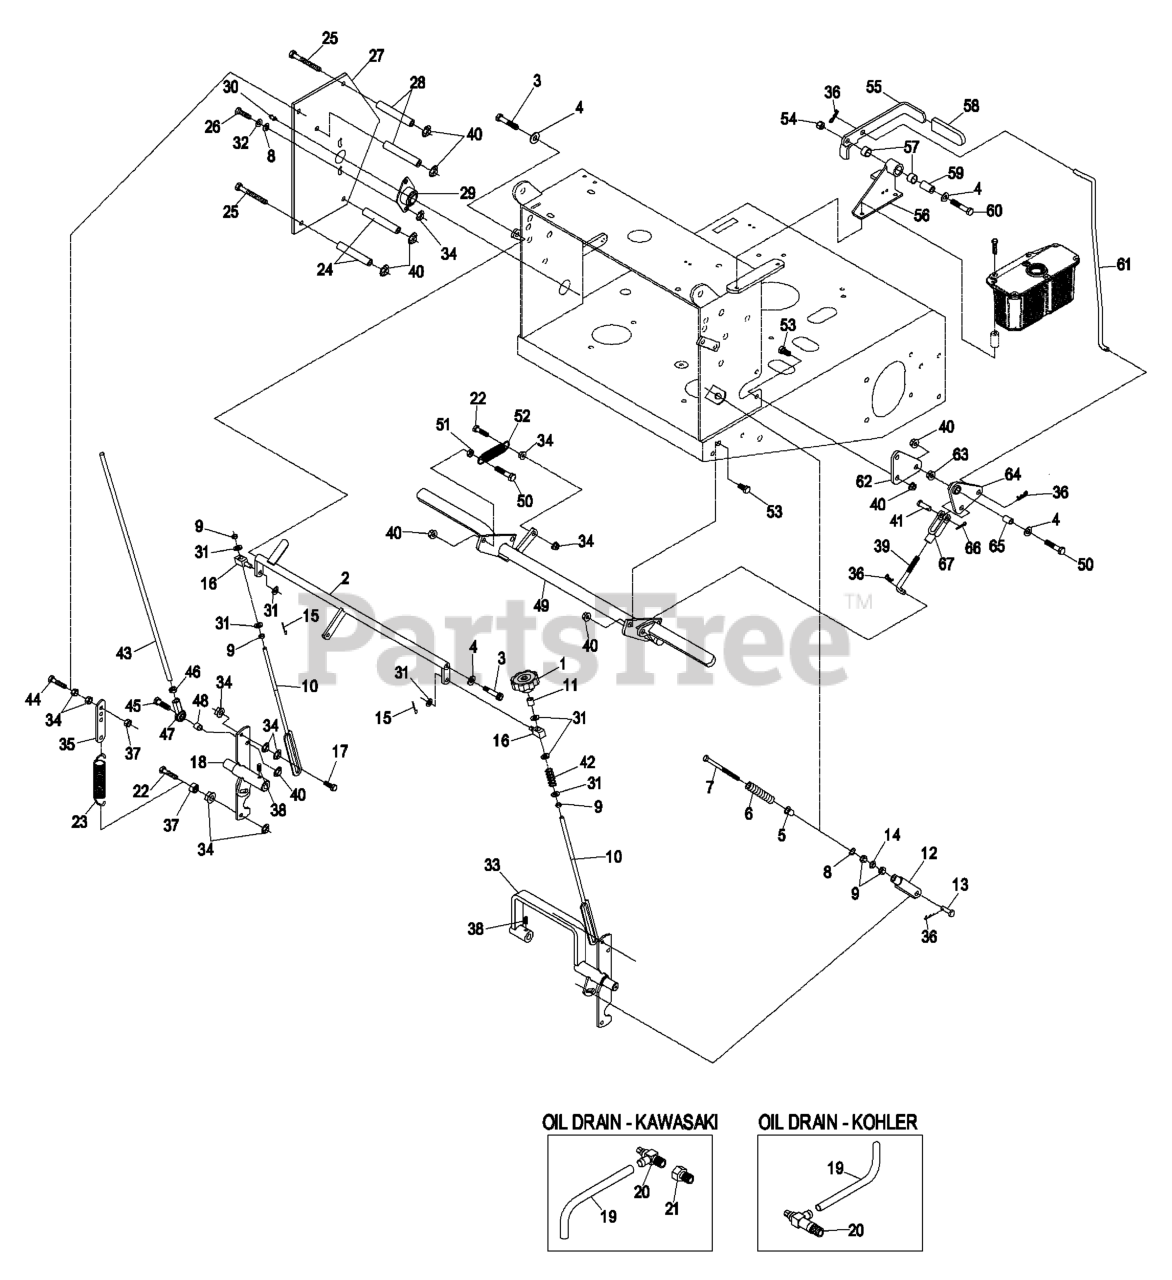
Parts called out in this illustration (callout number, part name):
1	KNOB-TRACKING
2	CRANK-CONTROL, SPEED
3	SCREW-HSH
4	WASHER-FLAT
5	BUSHING-FLANGED
6	SPRING,COMPRESSION (NEUT)
7	BOLT-RETURN, NEUTRAL
8	WASHER-FLAT
9	NUT-HEX
10	LINK-CONTROL, SPEED
12	YOKE-ADJUSTABLE
13	PIN-CLEVIS
14	NUT-JAM
15	PIN-COTTER
17	SCREW-HH
18	SHAFT-CONTROL, LH
19	HOSE-DRAIN, OIL
20	VALVE-DRAIN, OIL
21	ADAPTER
22	SCREW-HH
23	SPRING-EXTENSION
24	SPACER-SHIELD
25	SCREW-HH
26	SCREW-HH
28	SPACER-SHIELD
29	BEARING-FLANGE, SIDE
30	FITTING-GREASE
31	WASHER-PLAIN
32	WASHER-LOCK
35	TAB-SPRING, EXTENSION
36	PIN-COTTER
37	NUT-LOCK, NI
38	SCREW-SET
39	LINKAGE-LOWER
40	NUT-HHF, WHIZ
41	PIN-CLEVIS
42	SPRING-COMPRESSION
43	LINKAGE,DRIVE (PLT)
44	BOLT-TAP, HH
45	SCREW-HH
46	NUT-HEX JAM, LH
47	JOINT-BALL END, LH
48	SPACER-TUBE, PUMP LINK
49	WLD,PARK BRAKE 32
50	SCREW-HH
51	NUT-JAM
52	SPRING-IDLER
53	SCREW-HH
54	NUT-LOCK, NI
56	BRACKET ASM
57	SLEEVE-BUSHING
58	GRIP-LEVER
59	BUSHING-PIVOT
60	SCREW-HH
61	LINKAGE-UPPER
62	BELLCRANK
64	BELLCRANK ASM
65	BUSHING-PLASTIC
66	PIN-COTTER
67	YOKE-LINKAGE, BRAKE
